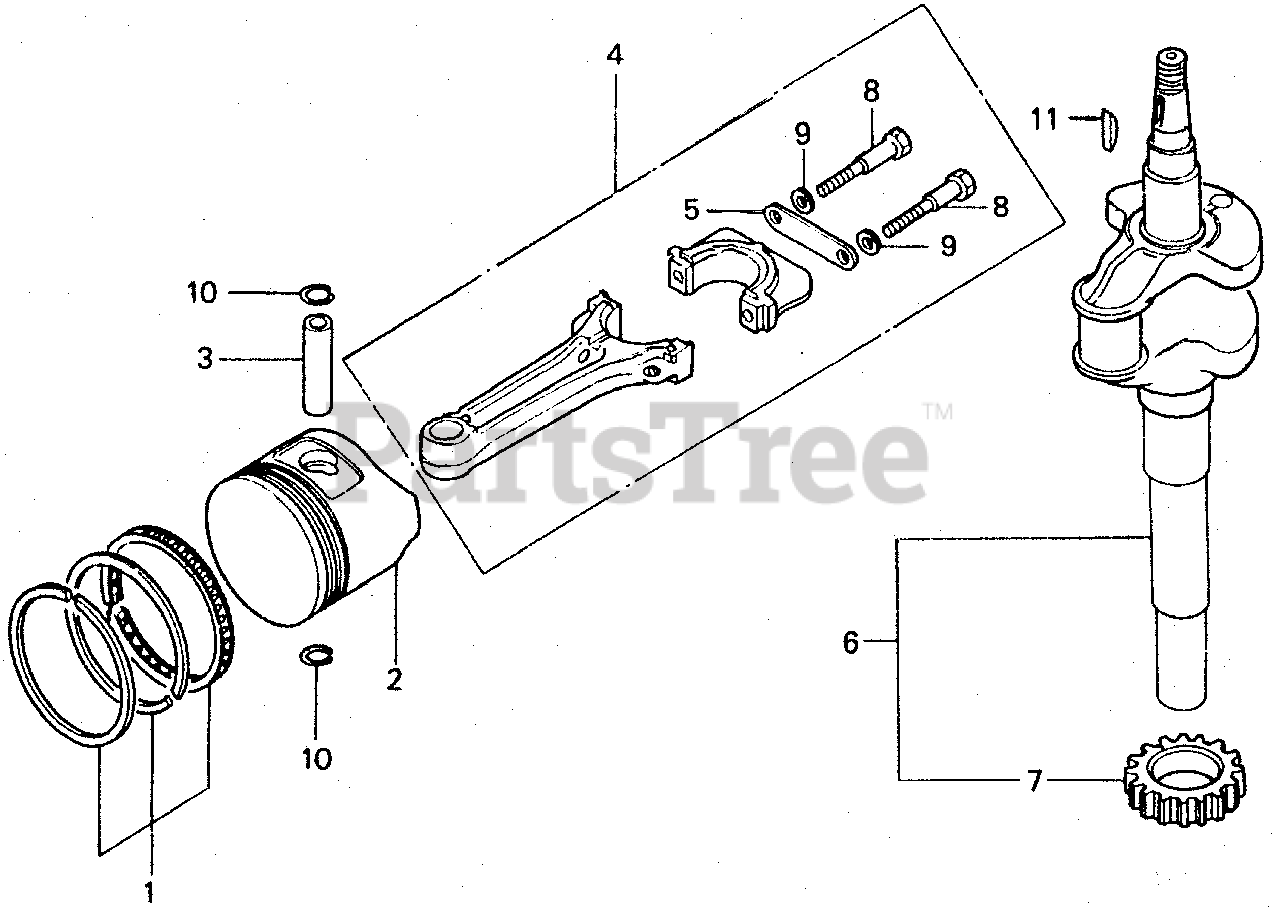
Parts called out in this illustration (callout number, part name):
1	RING SET, PISTON (STD)
1	RING SET, PISTON (0.25) (NOT AVAILABLE)
1	RING SET, PISTON (OS 0.50) (Honda Code 0635060). (OS)
1	RING SET, PISTON (0.75) (OS)
2	PISTON (STD)
2	PISTON (OS 0.25) (OS)
2	PISTON (OS 0.50) (OS)
2	PISTON (0.75) (OS)
3	PIN, PISTON
4	ROD ASSY., CONNECTING
4	ROD ASSY., CONNECTING (Honda Code 0871566). (US 0.25)
5	WASHER, CONNECTING ROD
6	CRANKSHAFT (NOT AVAILABLE)
7	GEAR, TIMING
8	BOLT, CONNECTING ROD (7MM)
9	WASHER, LOCK (7MM)
10	CLIP, PISTON PIN (15MM)
11	KEY, SPECIAL WOODRUFF (25X18)
